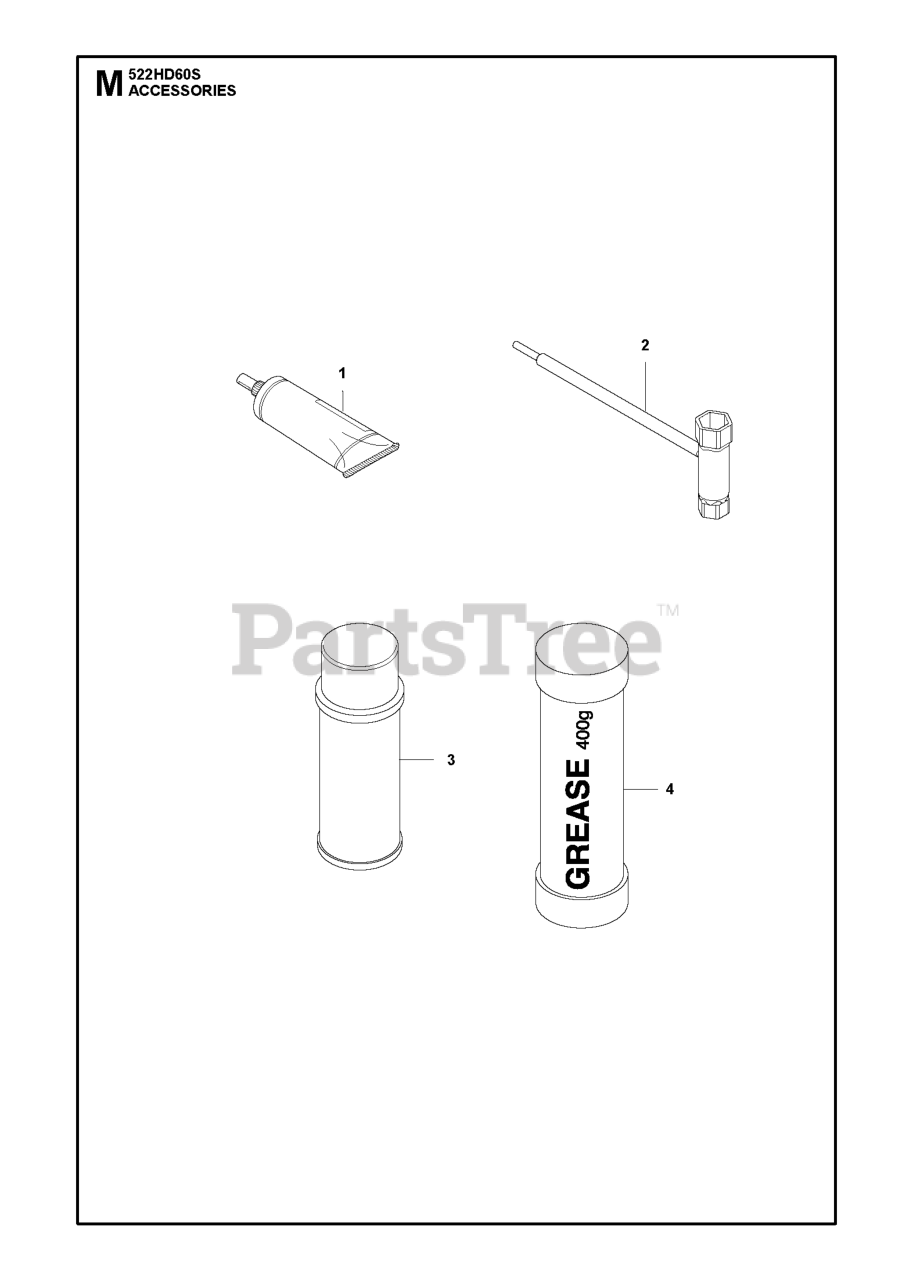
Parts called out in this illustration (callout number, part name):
1	GREASE ACCESSORY TUBE SHELL GA
2	COMBINATION WRENCH
4	HUS MULTI ADVANCE GREASE 400GR
